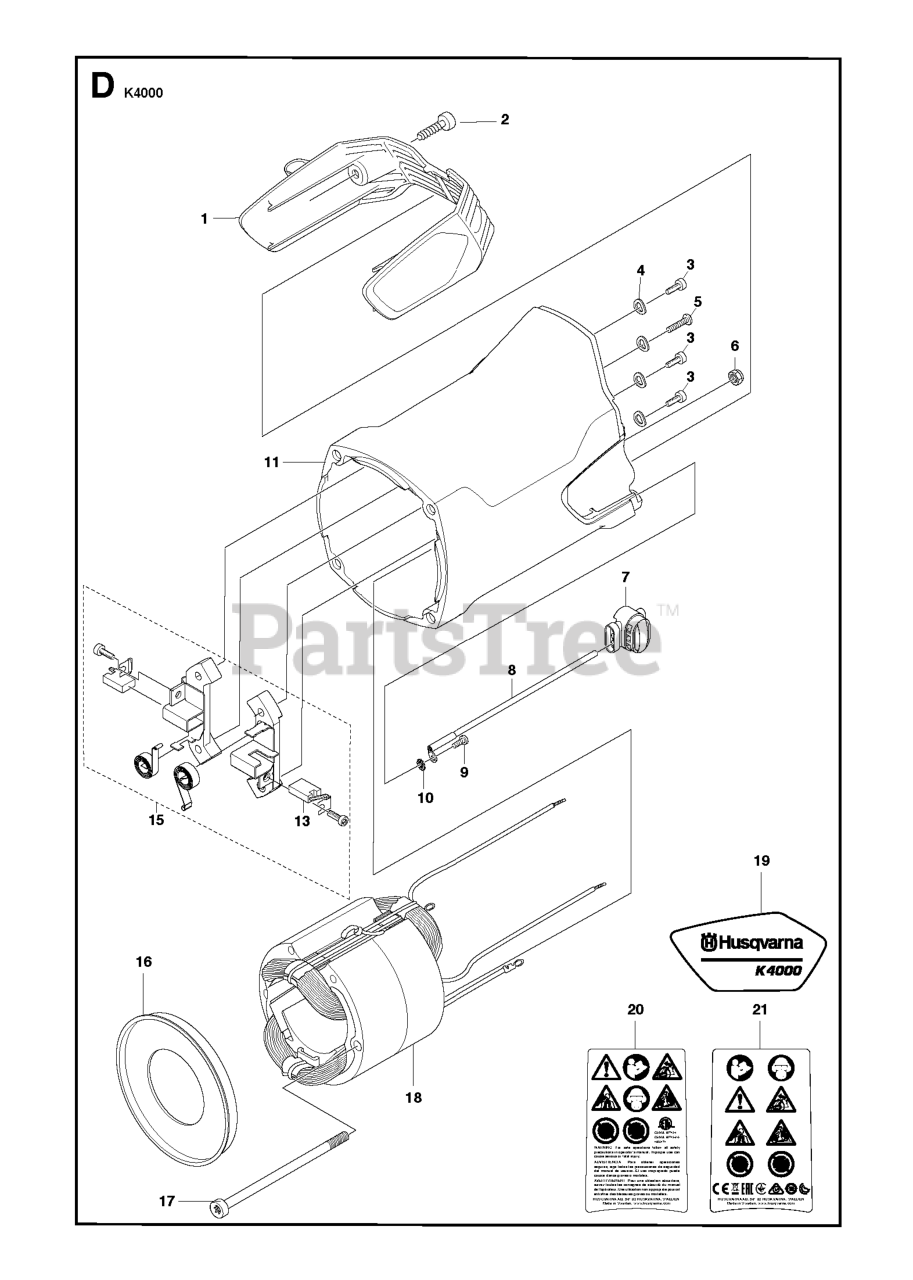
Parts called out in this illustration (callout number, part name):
3	SCREW ITXSCM
4	SPRING WASHER 4.3X8
7	SPLICE KIT
8	CABLE ASSY PE K3000
16	AIR STREAM DIRECTOR
